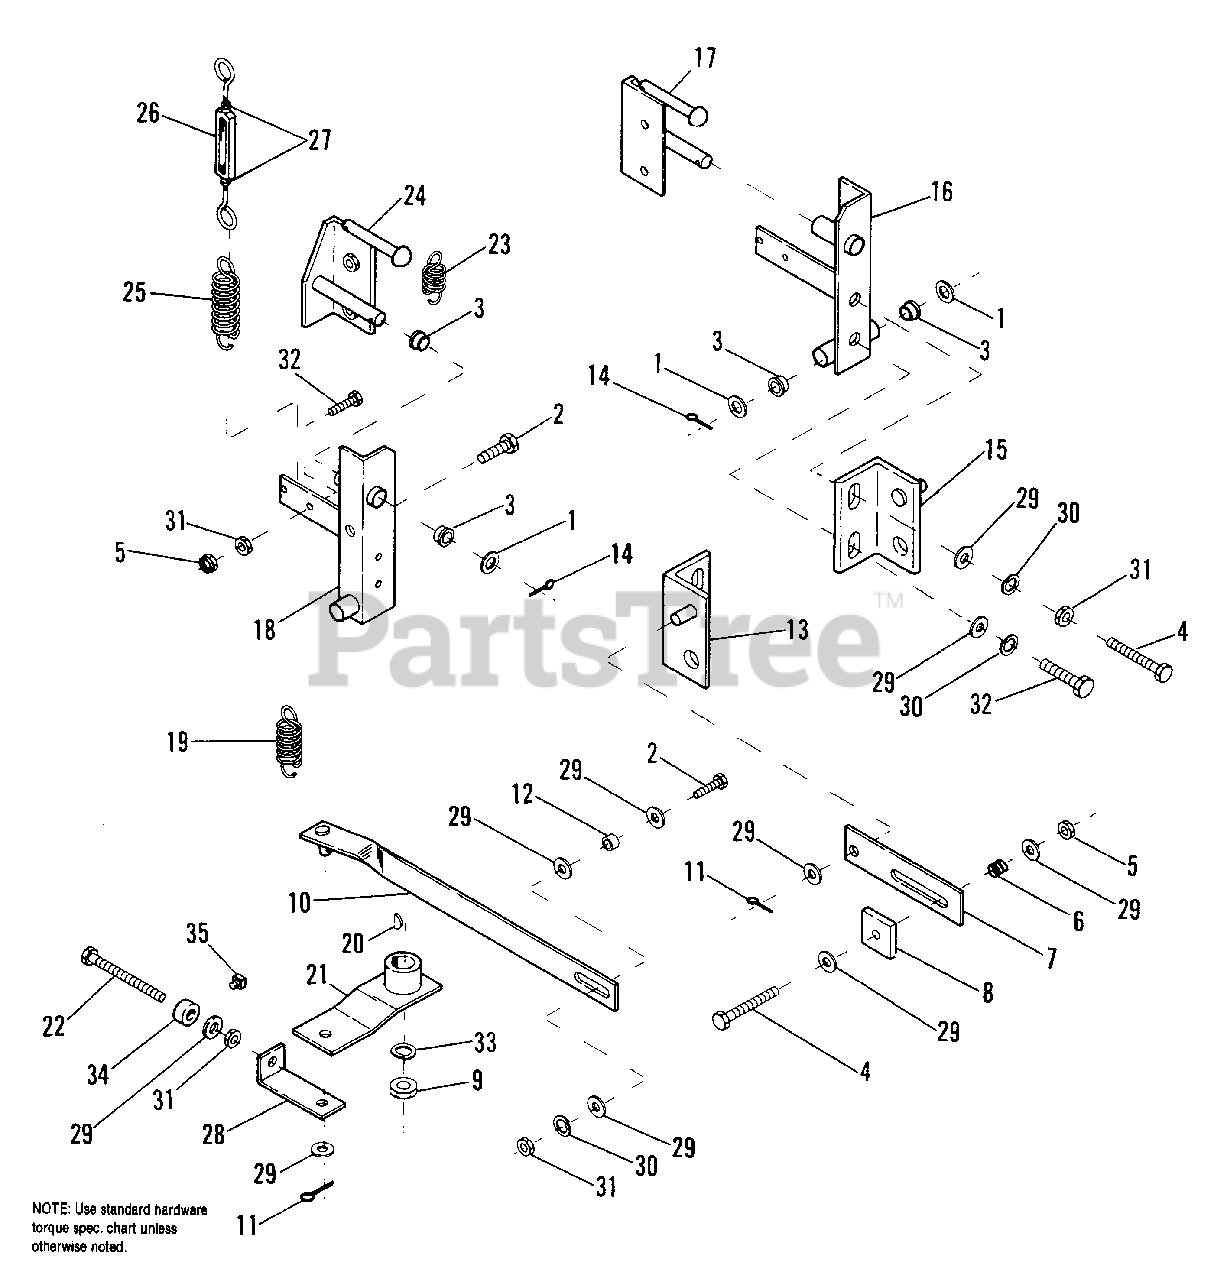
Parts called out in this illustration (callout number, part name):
1	WASHER, Plain
2	CAPSCREW, Hex, 5/16-18 x 1-1/4
3	BEARING, Flanged
4	CAPSCREW, Hex Head 5/16-18 x 2 G5
5	LOCKNUT, Unitorque, 5/16-18
6	SPRING, Friction
7	BAR, Friction
8	PAD, Friction
9	NUT, Hex, 3/8-16
10	LINK ASSY., Control
13	BRACKET ASSY., Speed Adjust, R.H.
15	BRACKET ASSY., Speed Adjust, L.H.
16	CONTROL ASSY., L.H.
17	JOINT ASSY., L.H.
18	CONTROL ASSY., R.H.
19	SPRING, Lower
20	KEY, Woodruff, 1/8-1/2
21	ARM ASSY., Control
22	CAPSCREW, Hex, 5/16-18 x 2-3/4
23	SPRING, Handle
24	JOINT ASSY., R.H.
25	SPRING, Upper
26	TURNBUCKLE
27	NUT, Hex, 1/4-20
28	STOP ASSY., Forward Travel
29	WASHER, Plain
30	LOCKWASHER, Spring, 5/16
31	NUT, Hex, 5/16-18
32	CAPSCREW, Hex, 5/16-18 x 1
33	LOCKWASHER, Spring, 3/8
35	SET SCREW, Sq. Hd., 1/4-20 x 3/8
